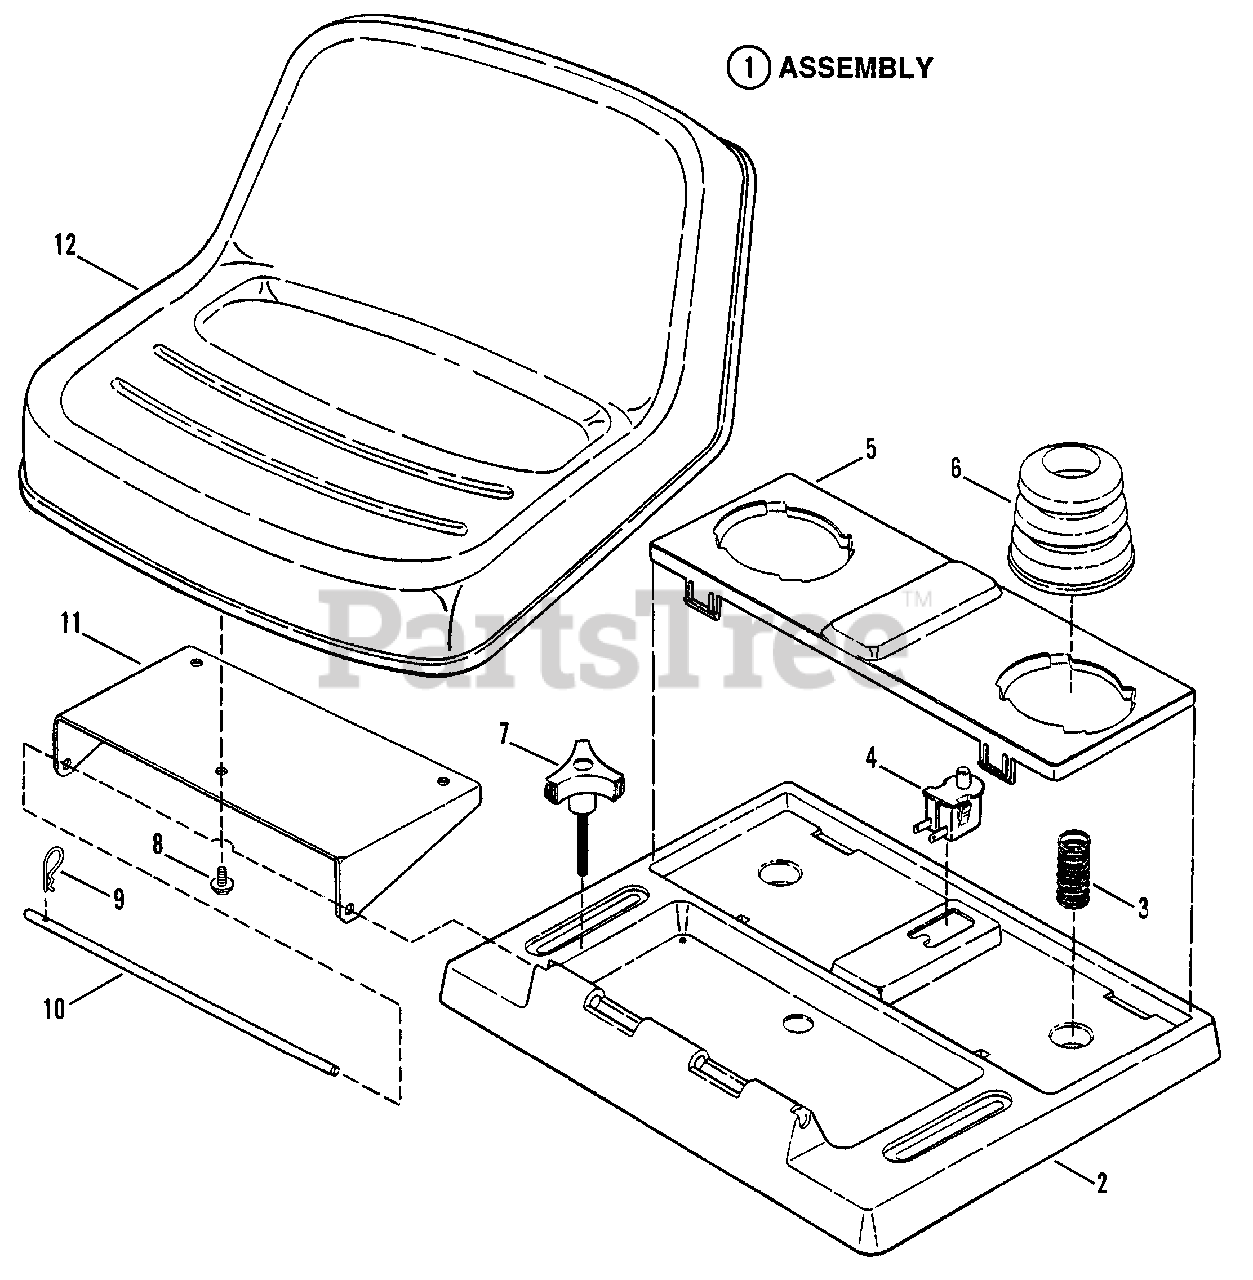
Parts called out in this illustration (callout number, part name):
1	ASSEMBLY, Seat Support
2	SUPPORT, Seat
3	SPRING
4	SWITCH, Seat
5	HOLDER, Cushion
6	CUSHION, Seat
7	KNOB, Seat Adjustment
8	BOLT, 5/16-18 x 1/2" Hex Flange Lock
9	PIN, Hair
10	ROD, Seat Hinge
11	BRACKET, Seat Support
12	SEAT, Operator's
